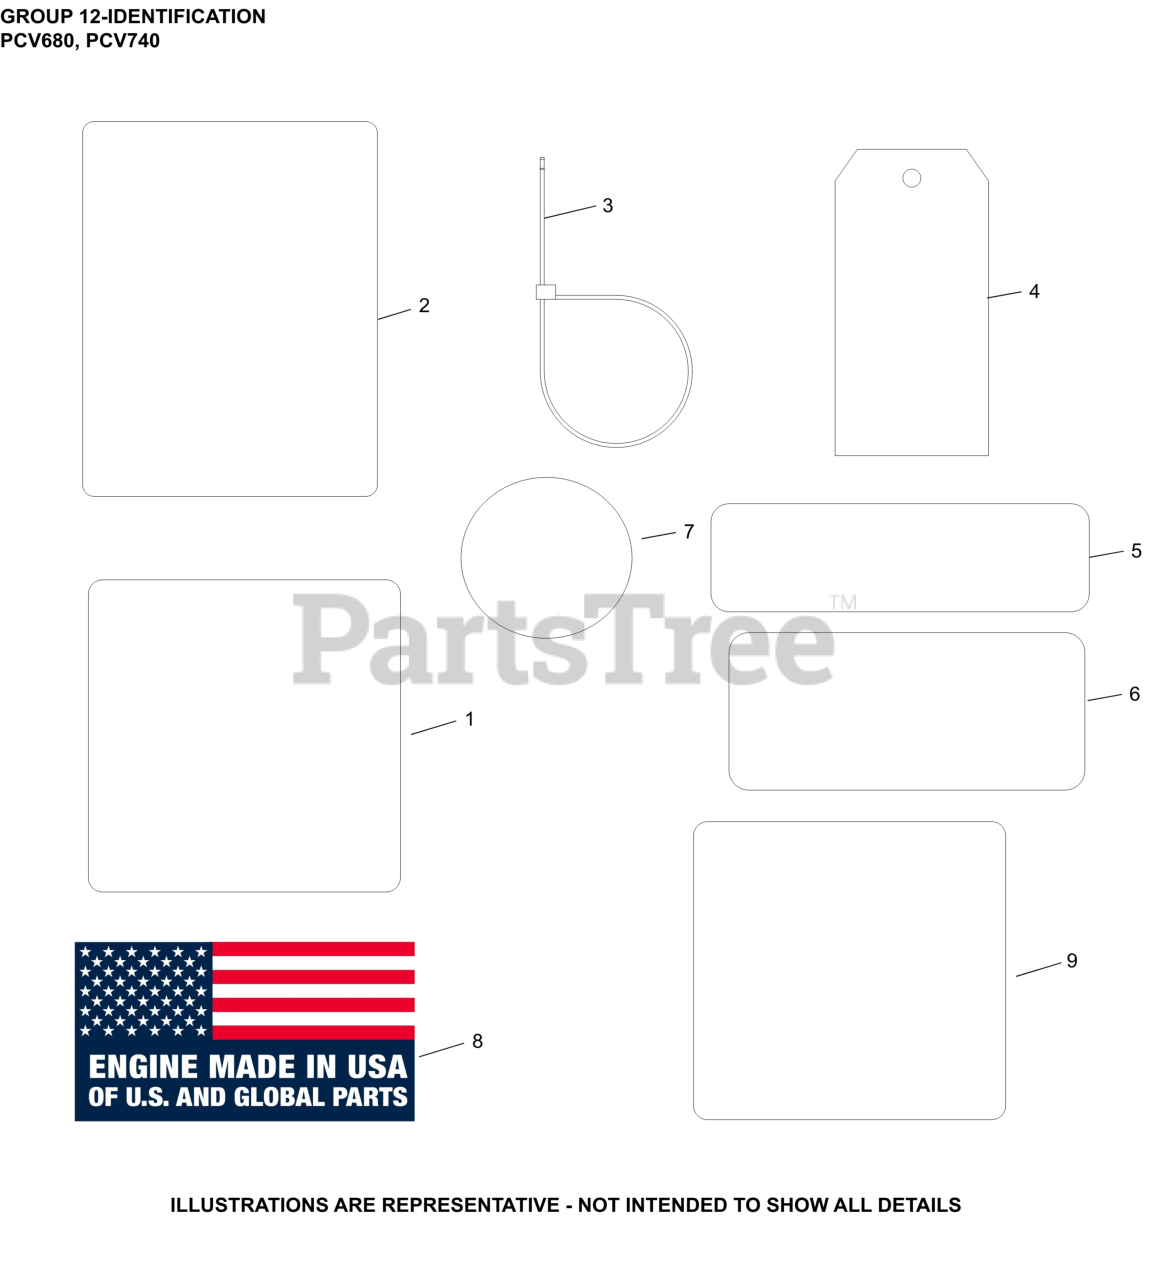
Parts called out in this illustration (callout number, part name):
2	LABEL, CLEAR LAMINATION
6	DECAL, SYNTHETIC OIL
8	DECAL, USA
9	LABEL, LOW EMISSION PCV680LE
